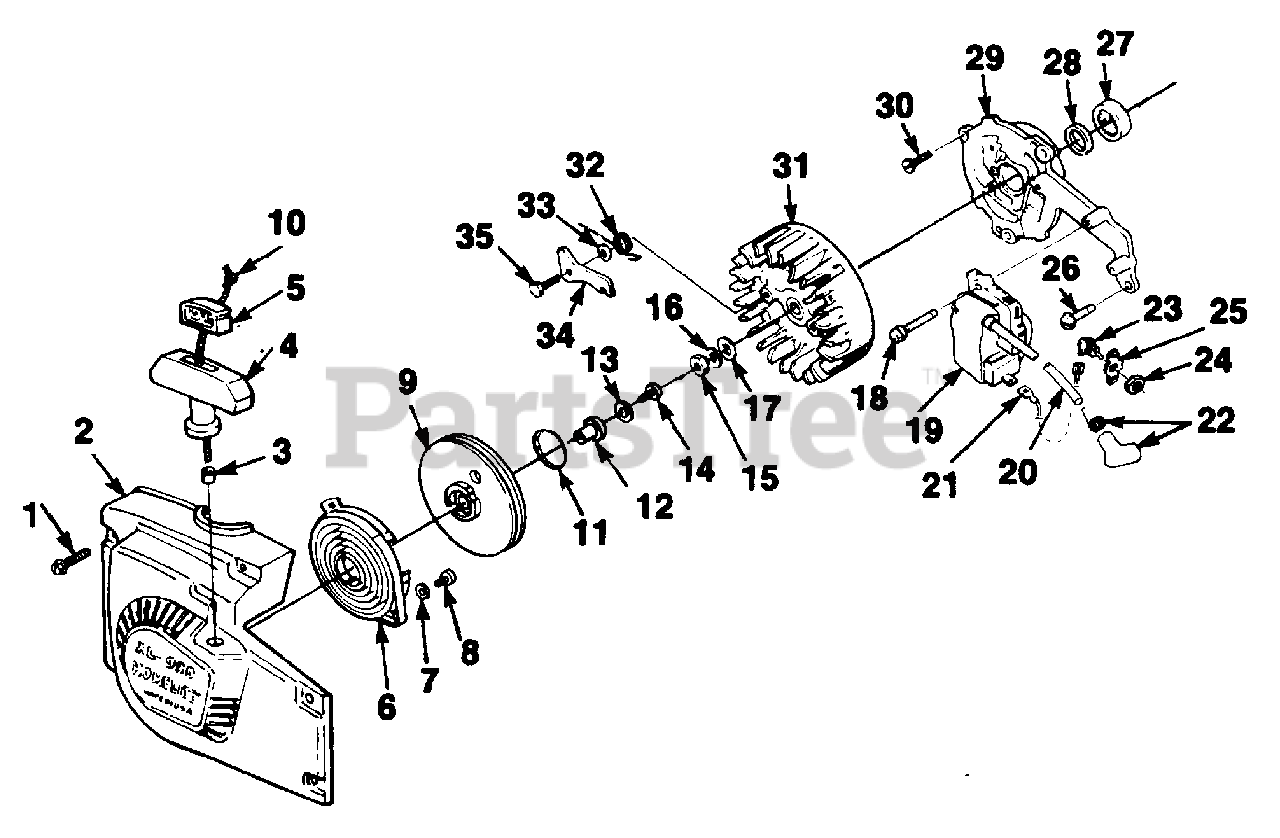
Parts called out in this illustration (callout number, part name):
2	HOUSING- Starter w/bushing
3	BUSHING
4	GRIP-Starter
6	SPRING & RETAINER
8	SCREW- Thd. form. (6-32 x 3/8")
9	PULLEY & CUP
10	STARTER ROPE
11	SPRING- Grip
12	BUSHING- Starter rope
13	WASHER- Flat
14	SCREW- (10 x 7/8")
15	NUT- Hex (3/8-24)
16	WASHER- Lock (3/8")
17	WASHER- Flat (3/8")
18	SCREW- Sems Hex hd. (8-32 x 1")
19	MODULE- Ignition
20	LEAD- Hi-Tension
21	LEAD- Ground
22	TERMINAL- Spark plug
23	SWITCH- Grounding
24	NUT
25	PLATE- Indicating
26	SCREW- Sems Hex hd. (1/4-20 x 3/4")
27	BEARING- Roller
28	SEAL
29	PLATE- Back
30	SCREW- (1/4-20 x 5/8")
32	SPRING- Starter pawl
33	WASHER- Flat
34	STARTER PAWL
35	SCREW- Shoulder
